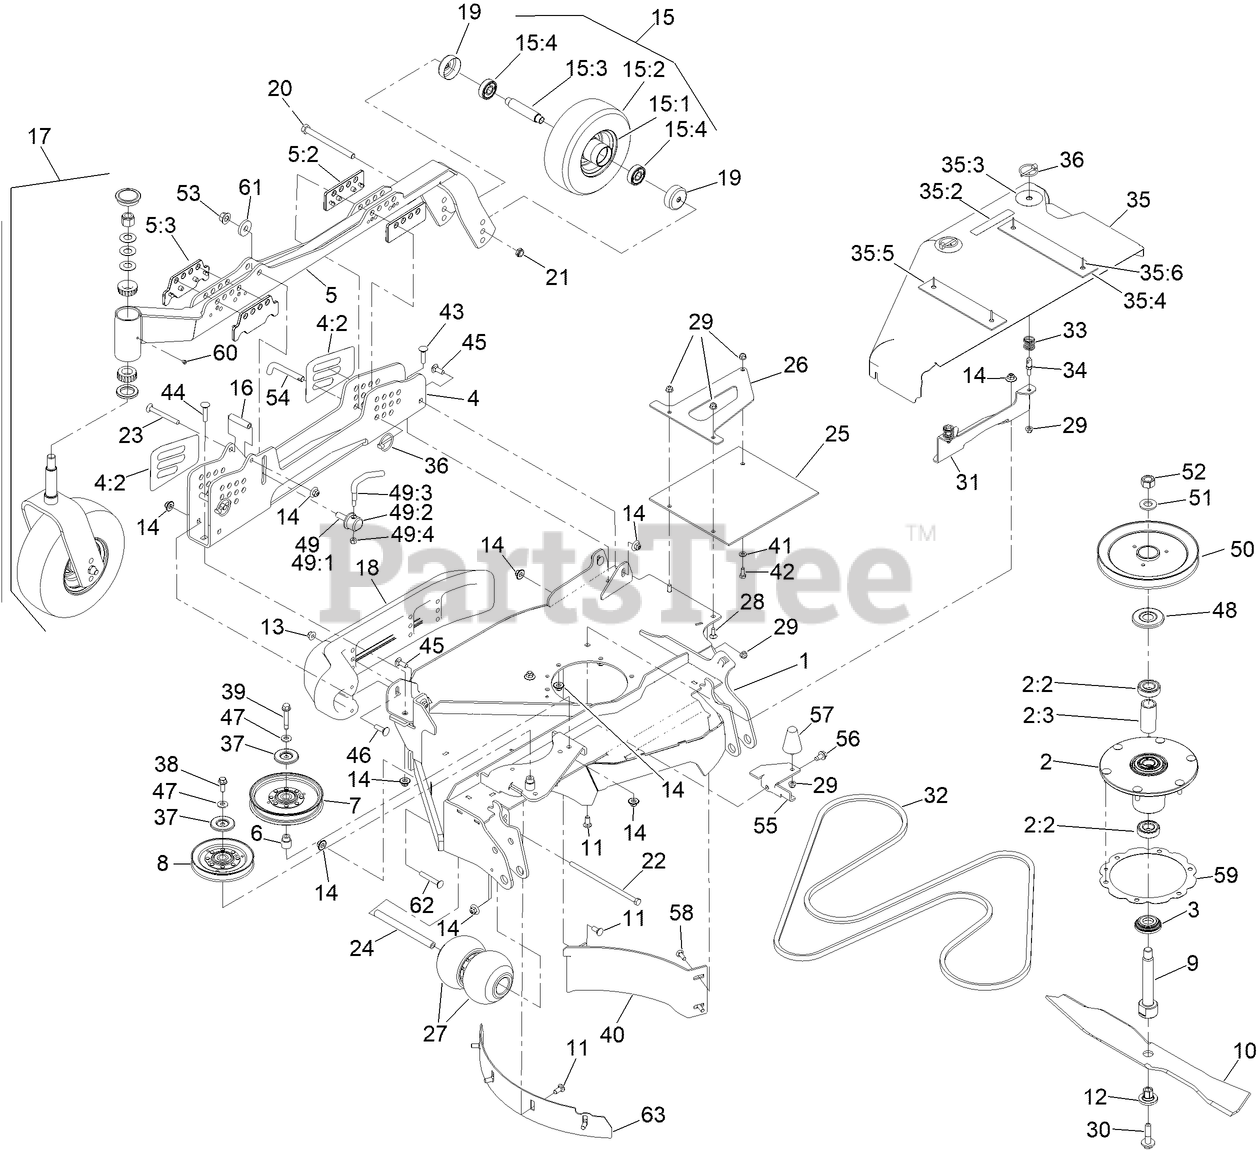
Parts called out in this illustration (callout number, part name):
1	ASM-DECK RH WING 96T
2	SPINDLE ASM
2:2	BEARING-BALL
2:3	SPACER-BEARING
3	GUARD-BOTTOM
4	ASM-CHANNEL, HOC RH W/DECALS
4:2	DECAL-HEIGHT OF CUT, RH
5	ASM-RH GAUGE WHEEL ARM
5:2	PLATE-GUIDE, REAR
5:3	PLATE-GUIDE, FRONT
6	BUSHING-IDLER
7	IDLER-PULLEY
8	IDLER-V
9	SHAFT-SPINDLE
10	BLADE-24.50 MULCH
11	BOLT-CARR
12	BUSHING-HEX
13	NUT-HF, NI
14	NUT-FLANGE, NI
15	WHEEL AND TIRE ASM
15:1	WHEEL
15:3	AXLE-CASTER
15:4	BEARING
16	SPACER
17	CASTER WHEEL ASM
18	SKID-BUMPER, DECK
19	GUARD, SEAL
20	SCREW-HH
21	NUT-HEX
22	SCREW-HH
23	SCREW-CARR
24	SPACER-WHEEL
25	GUARD-TIRE
26	SUPPORT-FLAP, RH
27	ROLLER-SCALP, ANTI
28	SCREW-CARR
29	NUT-HF, NI
30	SCREW-SEMS
31	BRACKET-SHIELD MOUNT, OUTER
32	BELT-V
33	SPRING
34	PIN, SPRING
35	RH WING SHIELD ASM
35:2	DECAL-NO STEP
35:3	DECAL-SCRATCH COVER
35:5	PLATE-FRONT
35:6	RIVET-POP
36	PIN-LYNCH
37	SHIELD-DUST
38	SCREW-HHF
39	SCREW-HHF W/ PATCH
40	BAFFLE-BLOCK, RH WING
41	WASHER-PLAIN
42	SCREW-HH
43	SCREW-CARR
44	SCREW-CARR
45	BOLT-CARR
46	BOLT-CARR
47	WASHER-BELLEVILLE
48	GUARD-BEARING, TOP
49	LEVER ASM
49:1	SCREW-LOCK
49:2	CAP-LOCK
49:4	NUT-LOCK, NI
50	SHEAVE-DRIVE, BLADE
51	WASHER
52	NUT-HEX
53	NUT-LOCK
54	PIN-HOC
55	BRACKET-COVER RETAINER
56	SCREW-HWH
57	BUMPER-RUBBER
58	SCREW-CARR
59	RING-SPACER, HOUSING
61	WASHER
62	SCREW-CARR
63	BAFFLE-DEPTH, RH
